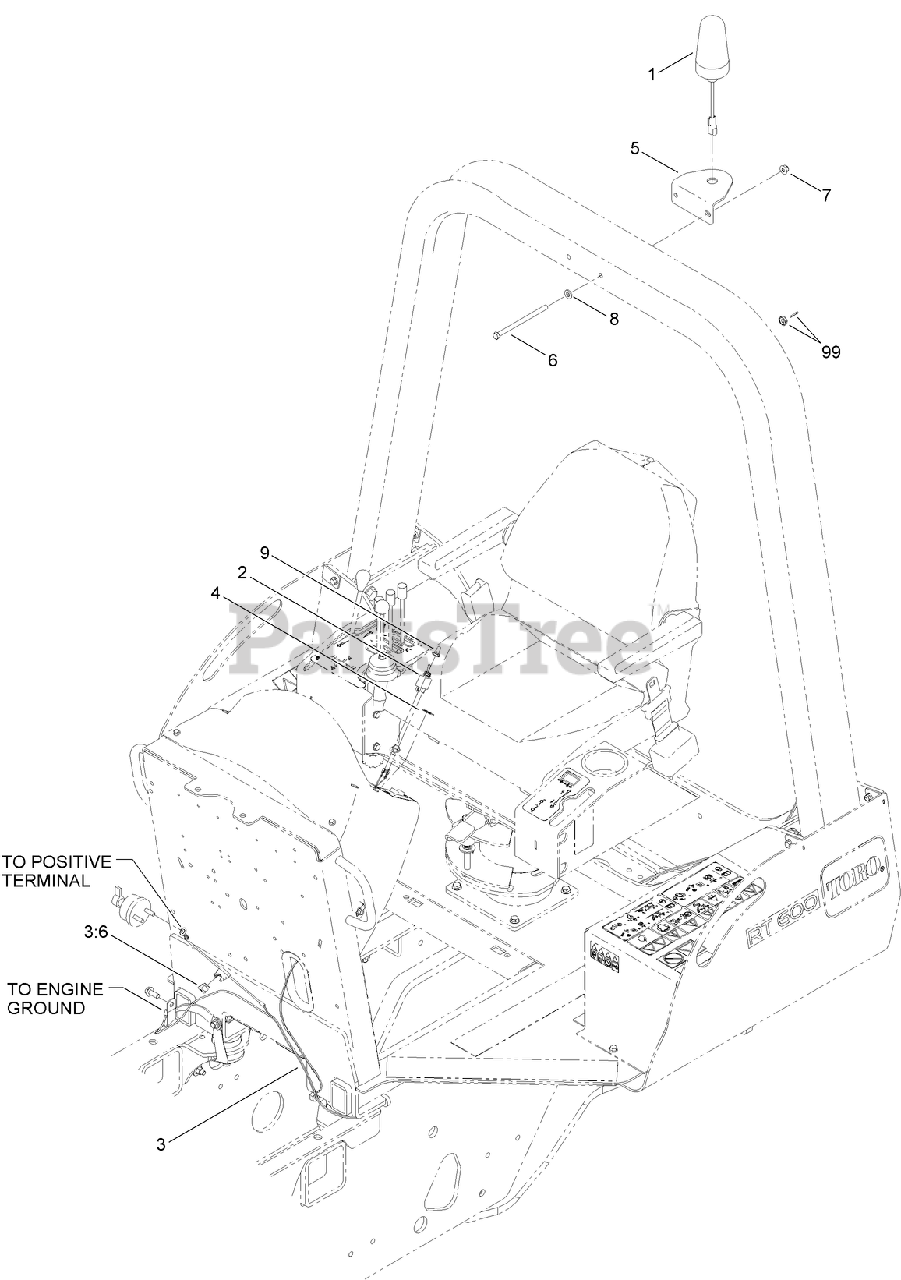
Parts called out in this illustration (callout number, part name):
1	LIGHT-STROBE
2	SWITCH
3	HARNESS-BEACON
3:6	FUSE-BLADE, 10 AMP
4	DECAL-BEACON
5	PLATE-BENT
6	BOLT-TAP, HH
7	NUT-HEX FLG
8	WASHER-HARDENED
9	BOOT-TOGGLE SWITCH
99	MOUNT-TIE WRAP, MAGNETIC
99	TIE-CABLE
